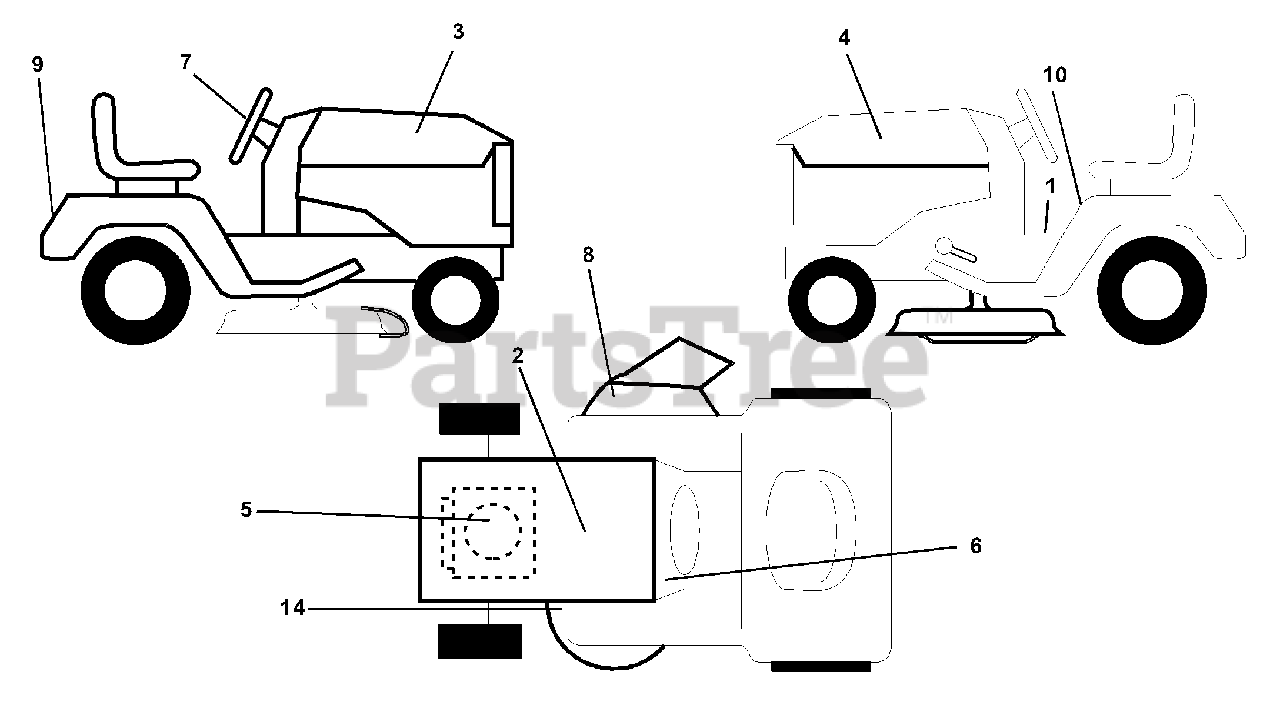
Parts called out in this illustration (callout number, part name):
1	Decal Oper. Step Thru E/F
2	Decal Battery
3	Decal Hood RH
4	Decal Hood LH
5	Decal HP Engine
6	Decal Dash Logo
7	Decal Wheel Steering
8	Decal Warning Multi-Languages
9	Decal Fender Husq
10	Decal Fender Danger E/F
14	Decal V-Belt Schematic
